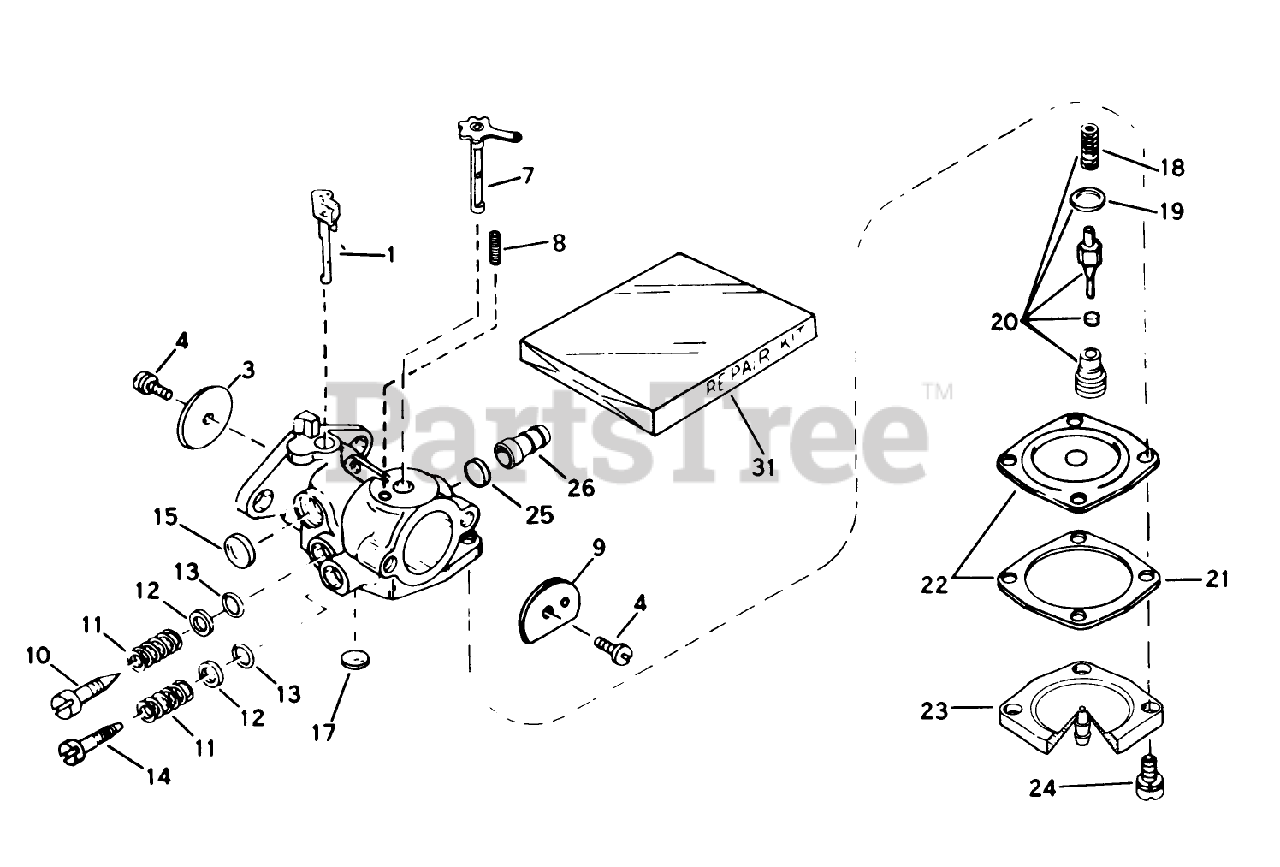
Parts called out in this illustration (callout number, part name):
1	Shaft/Lever-Throttle
3	Shutter-Throttle
4	Screw-Shutter
7	Shaft Lever Assembly
8	Spring-Positioning, Choke
10	Screw-Idle Adjustment
11	Spring
12	Washer
13	ORing
14	Screw Main Adjustment
15	Plug-Welch, Idle Mixture Well
17	Plug Welch
18	Spring-Valve
19	Gasket-Valve Seat
20	Inlet Needle, Seat, Spring Gasket Assy. (lncl. #1819)
21	Gasket-Diaphragm
22	Diaphragm Ass. (Incl. No. 21)
23	Cover-Diaphragm
24	Screw
26	Fitting-Fuel
31	Kit-Repair
